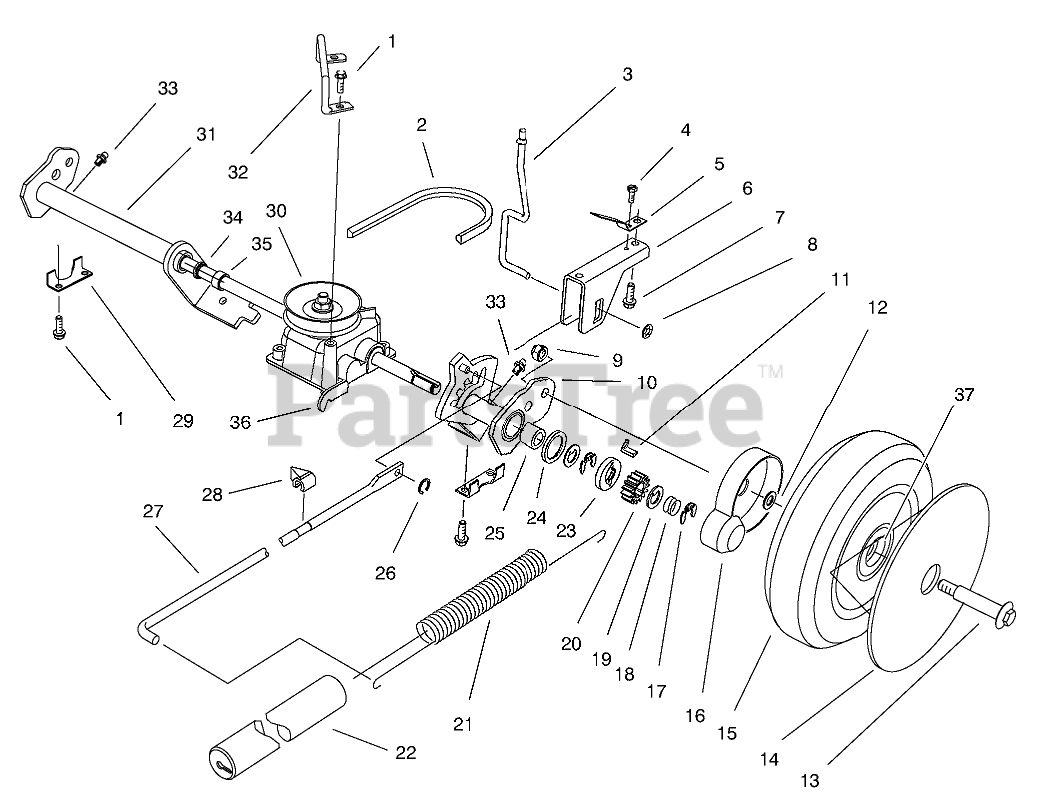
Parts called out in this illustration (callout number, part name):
1	SCREW-HWH
2	V-BELT
3	TRIGGER ROD
4	SCREW 8 - 32 X 250
5	SPRING - TRIGGER RET
6	SADDLE - HOC
7	SCREW
8	PUSHNUT
9	NUT-HEX
10	Arm-Pivot L.H. (Incl. Ref. #25, & 33-35)
11	KEY-ROCKING, LH
12	SPACER-COVER, WHEEL
13	BOLT-WHEEL
14	COVER-WHEEL
15	WHL & TIRE ASSEMBLY
16	COVER-WHEEL
17	RING-CLIP, LOCKING
18	SPRING-COMPRESSION
19	WASHER-THRUST, KEYED
20	GEAR-PINION
21	SPRING-COUNTERBALANCE
22	COVER-SPRING
23	WASHER-CLUTCH
24	RING-FRICTION
25	BEARING-ROLLER
26	GRIP RING
27	LINK ROD
28	INDICATOR-HEIGHT OF CUT
29	REAR SECURING PLATE
30	GEAR CASE ASSY
31	Arm-Pivot R.H. (Incl. Ref. #25, & 33-35)
32	Retainer Belt
33	FITTING-GREASE
34	SEAL-OIL
35	BUSHING
36	TRACTION BRACKET
37	BUSHING
